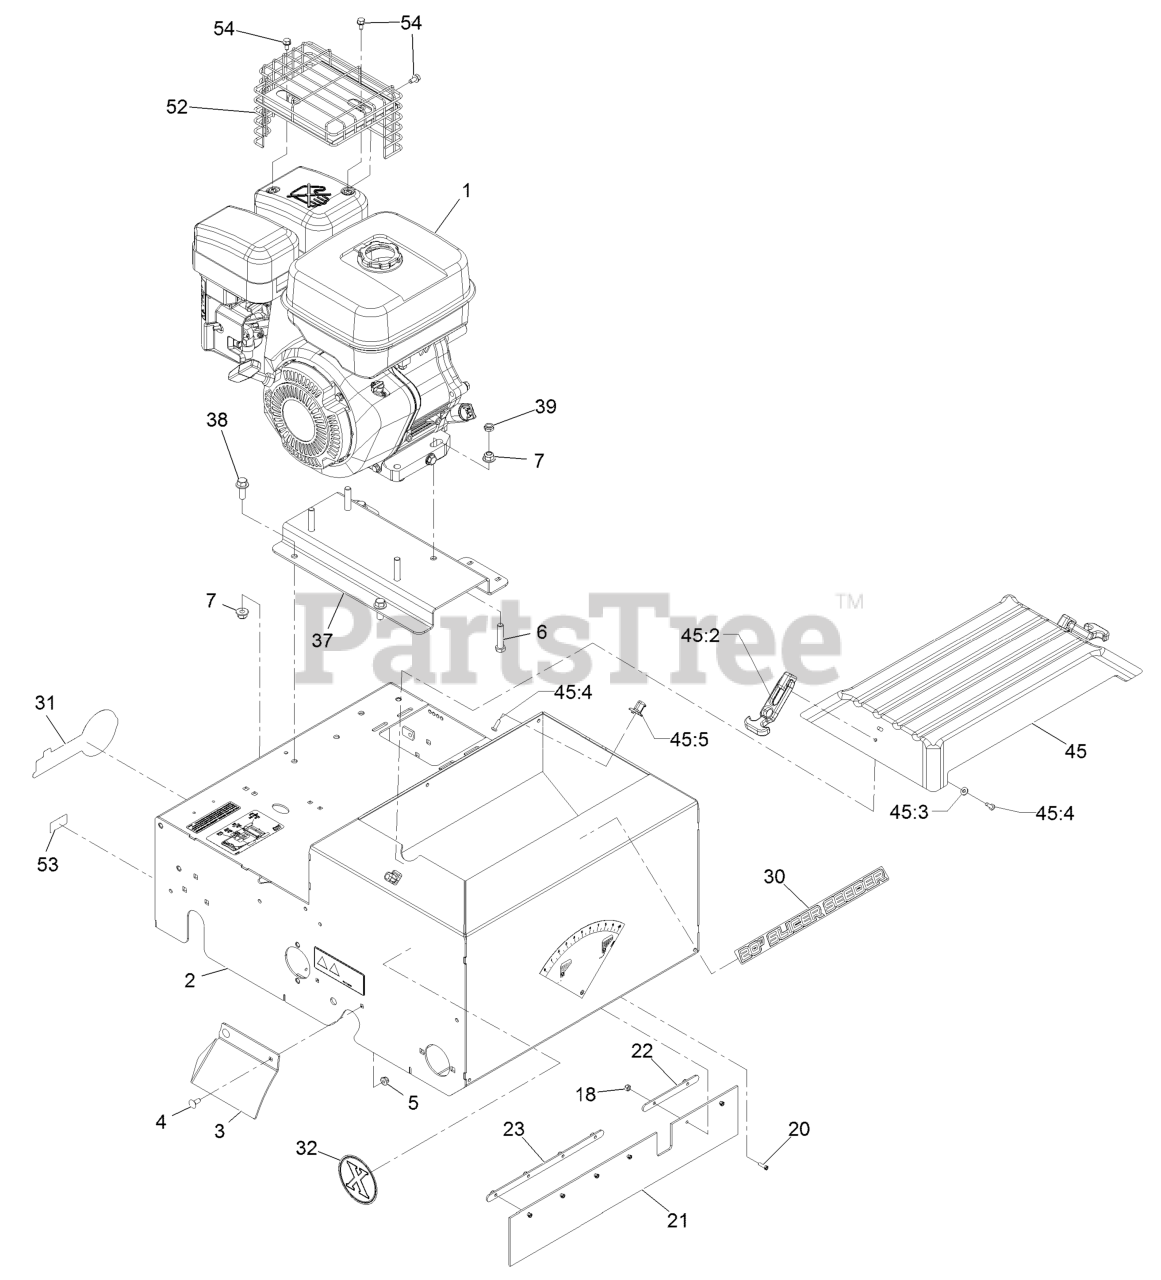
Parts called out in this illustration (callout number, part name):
2	FRAME ASM
4	SCREW-CARR
6	SCREW-HH
7	NUT-HF, NI
18	NUT-LOCK
20	SCREW-SHH
21	GUARD-DUST
22	PLATE-RETAINER
23	PLATE-RETAINER
30	Decal-Slicer Seeder Logo
31	DECAL, EXMARK LOGO
32	Decal-X-Logo
37	PLATE-ENGINE
38	SCREW-HHF 3/8-16 X 1
45	SEEDER COVER KIT
45:2	LATCH-RUBBER
45:3	WASHER-FLAT
45:4	SCREW-PPH
45:5	LATCH-KEEPER
52	GUARD, MUFFLER
53	Decal-Patent Ttco.Com
54	SCREW-HWH
